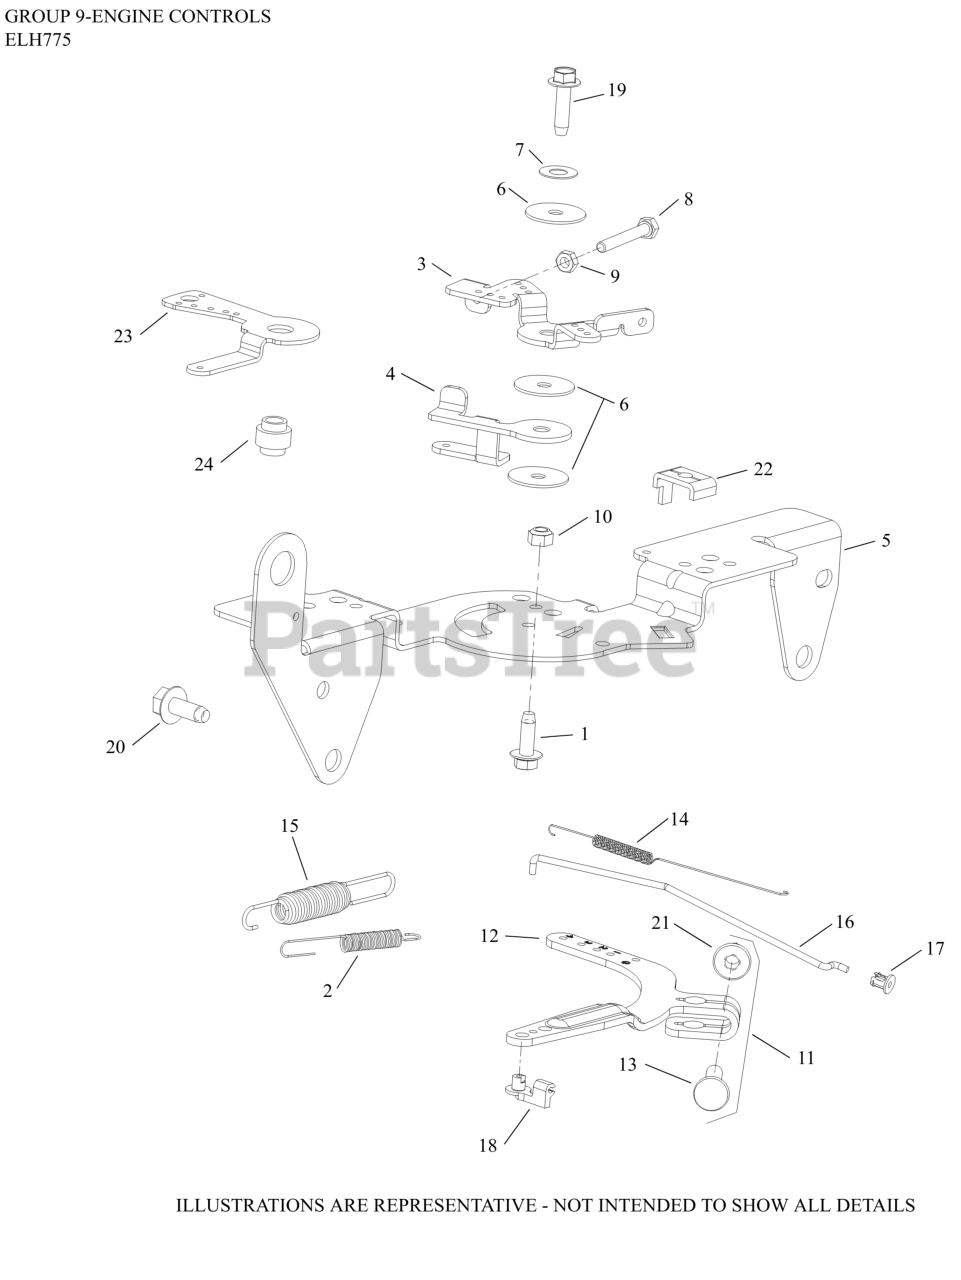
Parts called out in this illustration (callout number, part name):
1	SCREW, THREAD FORMING
2	SPRING, THROTTLE LIMITER
3	LEVER, THROTTLE CONTROL
4	LEVER, THROTTLE ACTUATOR
5	BRACKET, CONTROL
6	WASHER, FLAT 5.5 MM
7	WASHER, SPRING 1/4"
8	SCREW, CAP M4X.7X30
9	NUT, M4X0.7
10	NUT, LOCK M5X.8
11	LEVER, GOVERNOR ASSEMBLY
12	LEVER, GOVERNOR - (#2409069S)
13	BOLT, RD HD SQ NECK M6X1.0X25
14	SPRING, LINKAGE
15	SPRING, GOVERNOR (BLACK)
16	LINKAGE, THROTTLE
17	BUSHING, LINKAGE RETAINING
18	BUSHING, THROTTLE LINKAGE
19	SCREW, THD FRM-USE 25 086 473-S
20	SCREW, THREAD FORMING
21	NUT, FLG M6X1.0
22	CLAMP, CABLE-(#2523753S)
